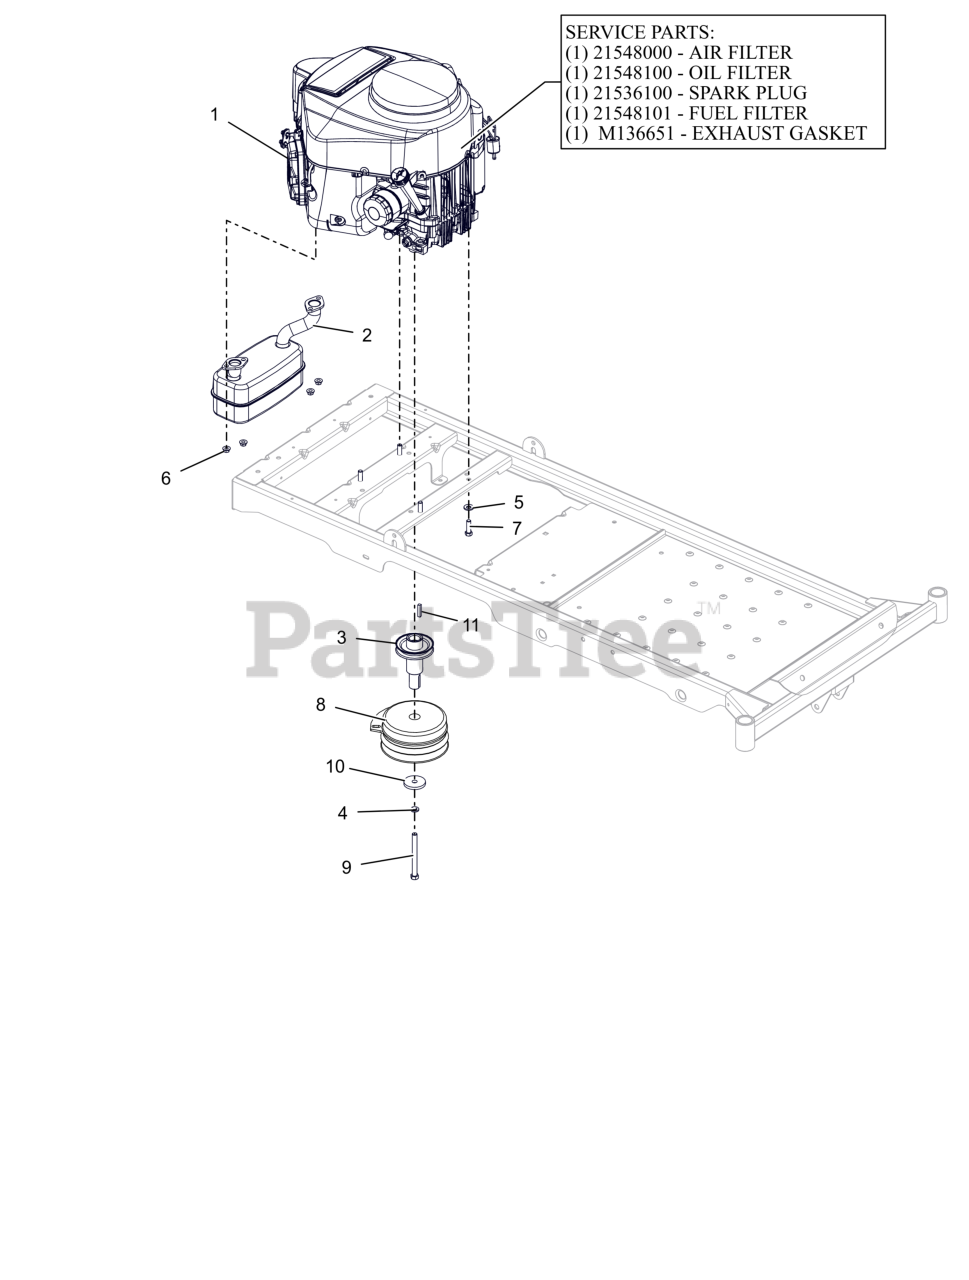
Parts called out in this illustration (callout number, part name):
1	ENGINE, KAWASAKI FR651V
1	AIR FILTER, KAWASAKI FR
1	OIL FILTER, KAWASAKI FR
1	PLUG, SPARK
1	FUEL FILTER-KAWASAKI FR
1	GASKET, MUFFLER #
2	MUFFLER, KAWI TWIN
3	WLDMT, CRANKSHAFT EXTENSION
4	WSHR, LK-REG .438X.109 ZCC
5	WASHER, 3/8" SPRING DISC
6	NUT-LK-TOP-FLG M8 ZCC
7	BLT, HEX .38-16X1.25 G5 ZCC NT
8	CLUTCH, 105 FT*LB MONO POLE
9	BLT, HEX .44-20X4.50 G8 ZCC NT
10	WSHR, FLT .469X2.00X.250 ZCC
11	KEY-SQ .25 X 1.25 X .25 SAE
